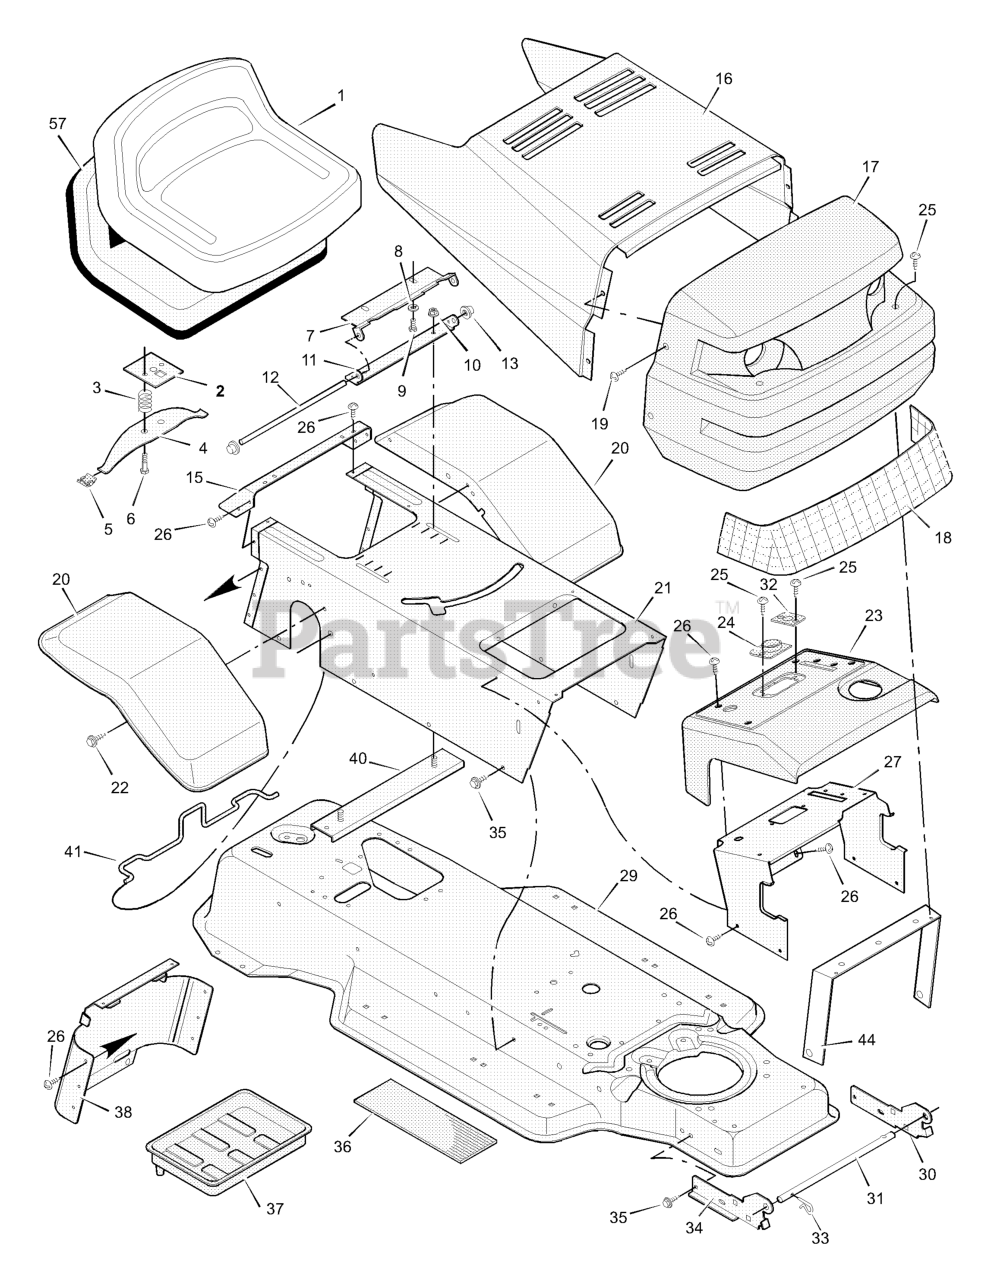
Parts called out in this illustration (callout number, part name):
2	Plate Assembly, Switch
3	Spring, Compression
4	Spring, Seat
5	Glide, Spring
6	Bolt, Shoulder
7	Support, Seat
8	Lockwasher
9	Bolt, Hex
10	Locknut, Flange
11	Bracket, Pivot
12	Rod, Pivot
13	Cap, Push On
15	Fender, Apron
17	Grille Assembly
21	Console Assembly
23	Dash Panel
24	Bearing, Steering
26	Screw
27	Support, Dash
29	Frame Assembly
30	Bracket, Left Grille
31	Rod, Pivot
32	Bearing
33	Pin, Hair
34	Bracket, Right Grille
37	Tray, Battery
38	Cap, Console
39	Bolt
40	Channel Assembly
41	Clamp, Battery
44	Brace, Grille
57	Pan, Seat (with foam)
